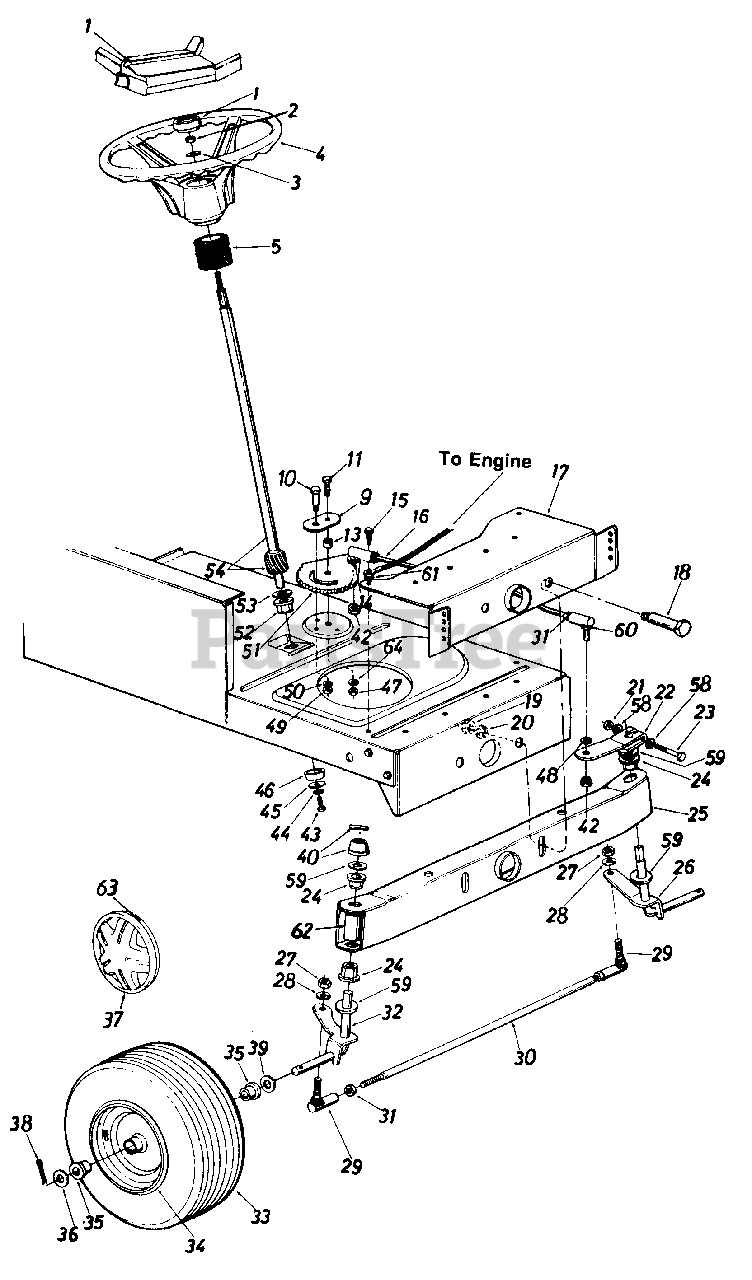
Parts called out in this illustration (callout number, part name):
1	Steering Wheel Cap
2	Hex L-Nut 5/16-24 Thd.
3	Belleville Wash. .345" I.D.
4	Steering Wheel
5	Steering Bellow 9"
9	Retainer Plate
10	Shoulder Bolt .437" Dia. x .35 Lg. 5/16-18 Thd.
11	Hex Bolt 3/8-24 x 1.0" Lg. (Grade 5)
13	Spacer .380" I.D. x .625" O.D. x .227
14	L-Wash. 3/8" I.D.
15	Hex Wash. Hd. Self-Tap Scr.
16	Steering Drag Link
17	Front Pivot Brkt.
18	Shoulder Bolt .498" Dia. x 2.04 Lg. 3/8-16 Thd.
19	Hex Nut 3/8-16 Thd.s
20	L-Wash. 3/8" I.D.
21	Hex Cent. L-Nut 5/16-24 Thd.
22	Steering Arm Front Axle
23	Hex Bolt 5/16-24 x 2.00" Lg. (Grade 5)
24	Hex Flg. Brg. .634 I.D.
26	Front Axle Ass'y. L.H.
27	Hex Nut 3/8-24 Thd.
28	L-Wash. 3/8" I.D.
29	Ball Joint 3/8-24 Thd.
30	Tie Rod
31	Hex Jam Nut 3/8-24 Thd.
32	Front Axle Ass'y. R.H.
33	Wheel Ass'y. Comp.
34	Front Wheel Rim Only
35	Bearing
36	Fl-Wash. .635 I.D. x 1.59" O.D.
37	Spoked Hub Cap
38	Cotter Pin 1/8" Dia. x 1.25"
39	Fl-Wash. .640" I.D. x 1.24" O.D.
40	Push Cap 5/8" Dia. Rod
42	Hex Jam Nut 3/8-24 Thd.
43	Hex L-Bolt 5/16-18 x .62"
44	L-Wash. 5/16" I.D.
45	Fl-Wash. .33" I.D. x 1.25" O.D.
46	Spacer (Plastic)
47	Hex Nut 3/8-24 Thd.
48	L-Wash. 3/8" I.D.
49	Hex Nut 5/16-18 Thd.
50	L-Wash. 5/16" I.D.
51	Steering Gear Segment
52	Hex Flg. Brg. .634 I.D.
53	Fl-Wash. (Hardened)
54	Steering Shaft
58	Wave-Wash. .32" I.D. x .62" O.D.
59	Fl-Wash. (Hardened)
60	Drag Link Ball Joint 3/8-24 Thd.
61	Ext. L-Wash. 5/16" I.D.
62	Plastic Tube
63	Spring Clip
64	Bell-Wash. .39" I.D. x 1.38" O.D.
